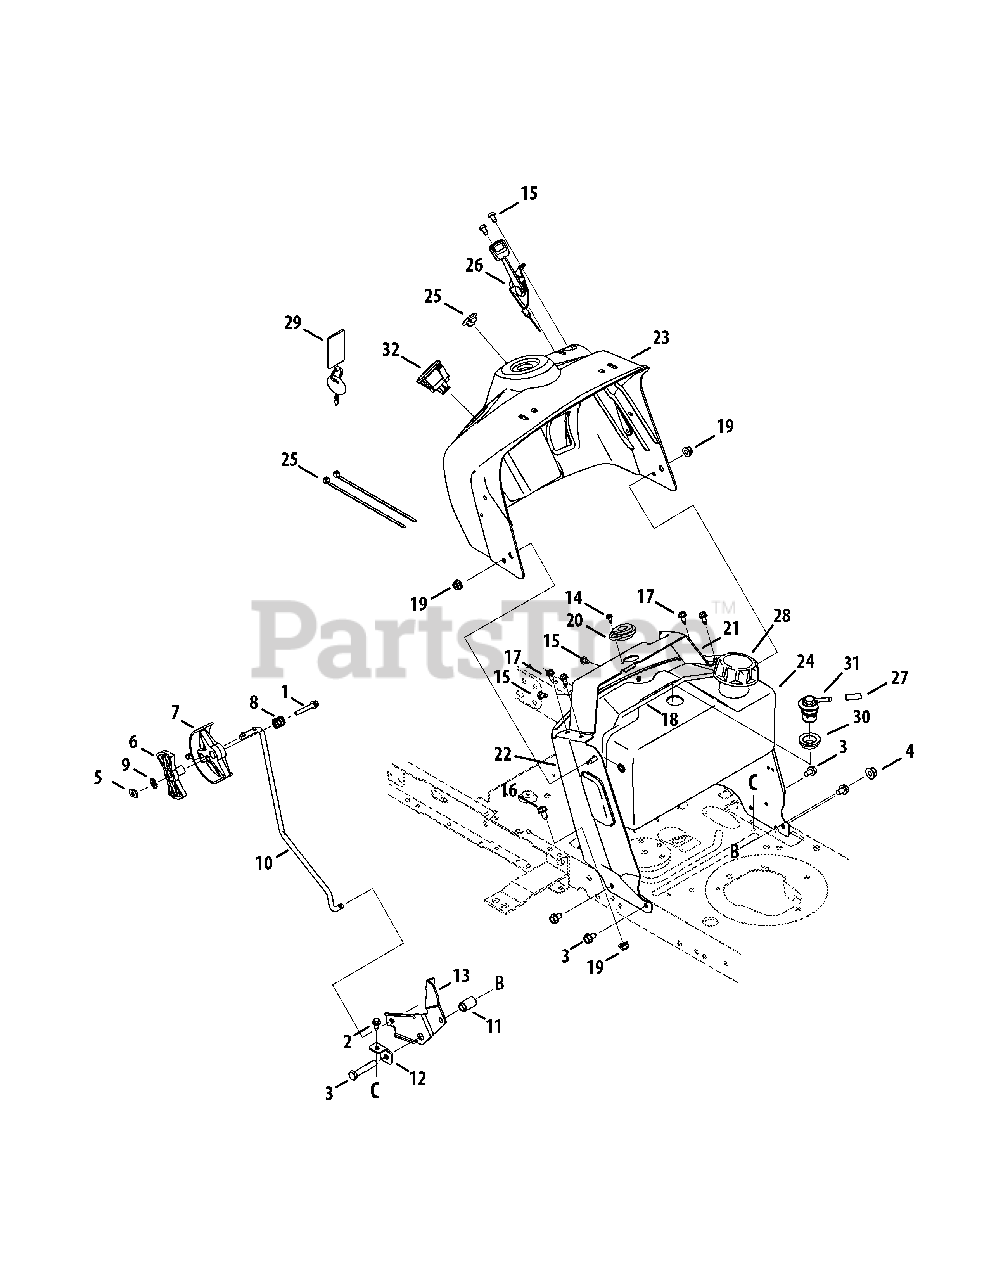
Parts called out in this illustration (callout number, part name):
1	Hex Head Screw, 1/4-20 x 1.50
2	Self-Tap Screw, 1/4-20 x .625
3	Hex Head Screw, 3/8-16 x 2.00
4	Flange Lock Nut, 3/8-16
5	Top Lock Weld Nut, 1/4-20
6	Index Control
7	Shift Lever
8	Compression Spring, .685 x .63
9	Internal Lock Washer, 1/4
10	Speed Control Rod
11	Flange Spacer, .390 x .671 x 1.095
12	Speed Latch Tab
13	Transmission Speed Latch, RMC
14	Screw, #10
15	Self-Tap Screw, 1/4-20
16	Self-Tap Screw, 5/16-18
17	Hex Washer Screw, 1/4-20 x .625
18	Fuel Tank Clamp Rod
19	Flange Lock Nut, 5/16-18
20	Steering Column Bearing
21	Steering Support Bracket
22	Lower Dash
23	Upper Dash Panel
24	Fuel Tank, 2 Gallons, EPA
25	Choke Plug
26	Throttle/Choke Assembly
27	Vent Hose
28	Fuel Cap
29	Key Assembly
30	Rubber Grommet
31	Fuel Rollover Valve
32	Key Switch Module
